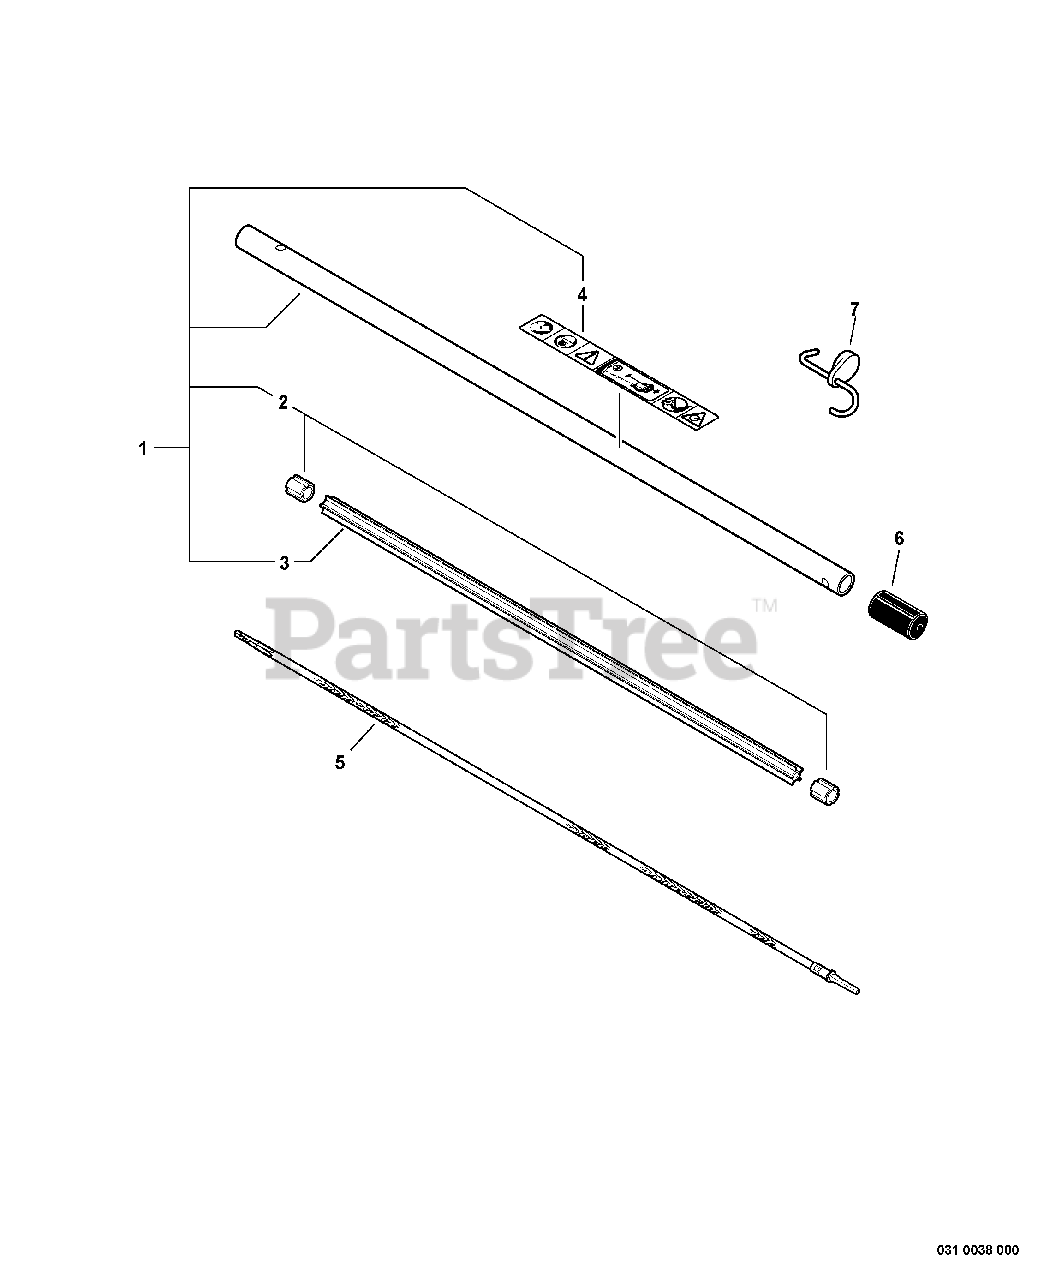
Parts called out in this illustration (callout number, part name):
1	MAIN PIPE ASSY
3	LINER - FLEXIBLE
4	LABEL, CAUTION
5	DRIVESHAFT - FLEXIBLE
6	CAP, MAIN PIPE
7	HANGER, ATTACHMENT
